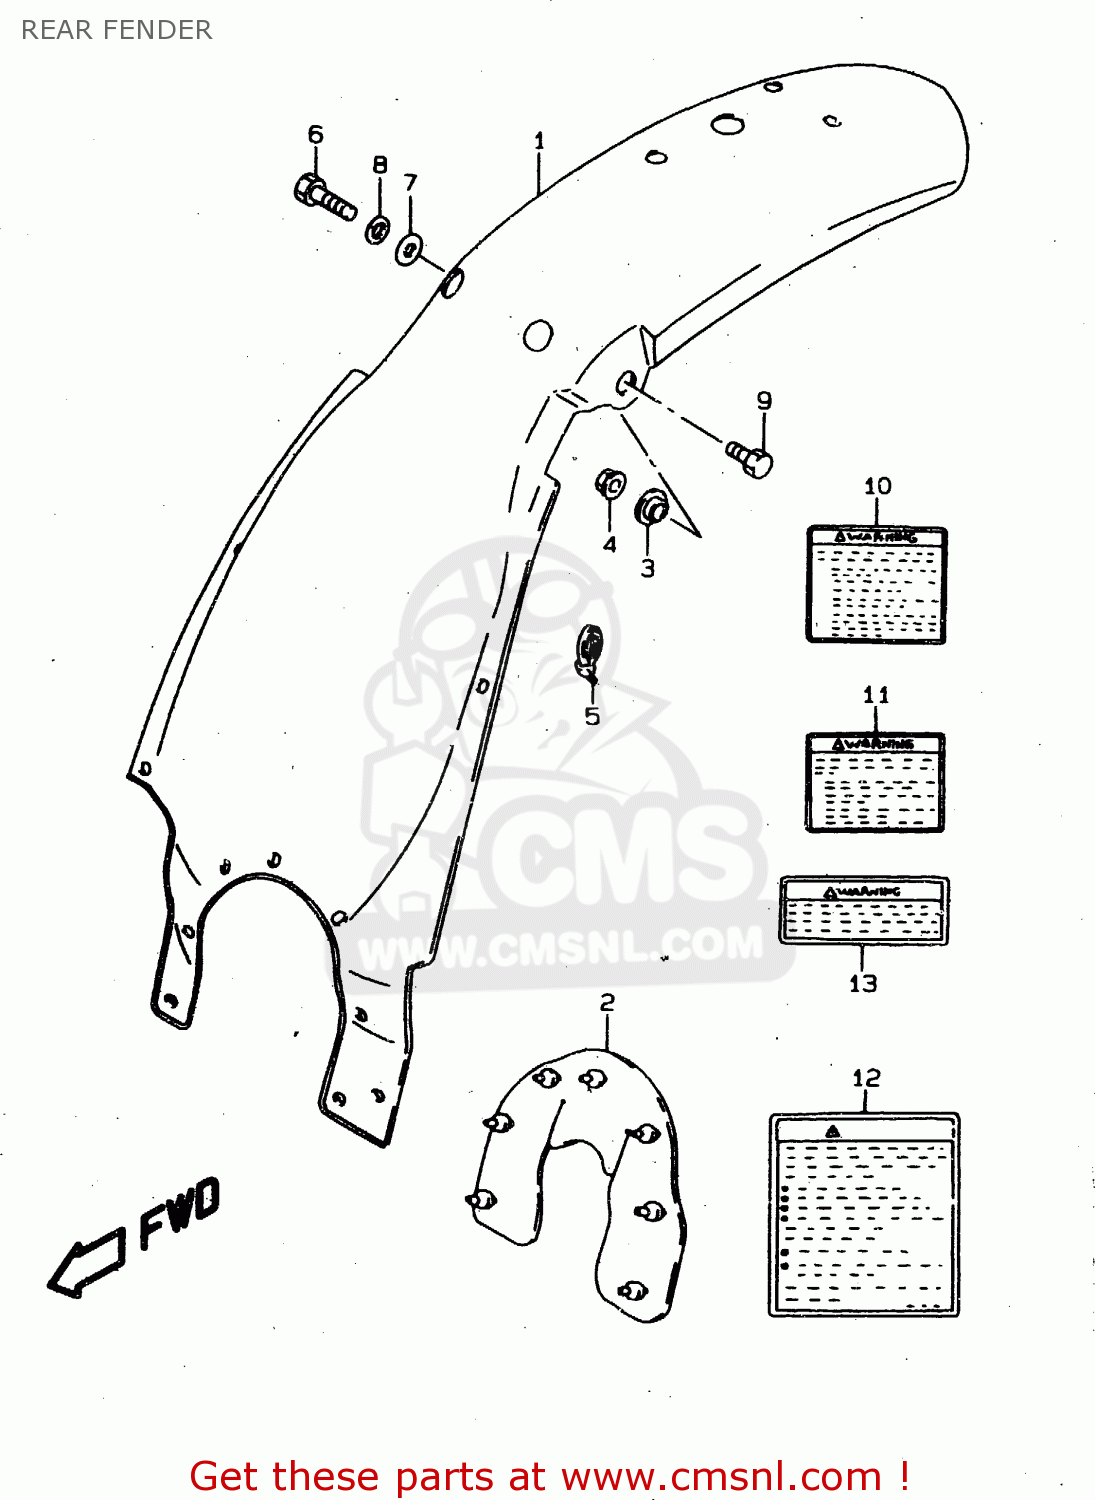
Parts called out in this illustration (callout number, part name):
1	FENDER,RR
2	MUDGUARD,RR FENDER
3	WASHER
4	NUT
5	CLAMP
6	BOLT
7	WASHER(8.5X28X1.6)
8	LOCK WASHER
9	BOLT
10	LABEL (WARNING)
11	LABEL, WARNING
12	LABEL, ATTENTION
13	LABEL (MANUAL NOTICE)
14	MANUAL, OWNER'S
